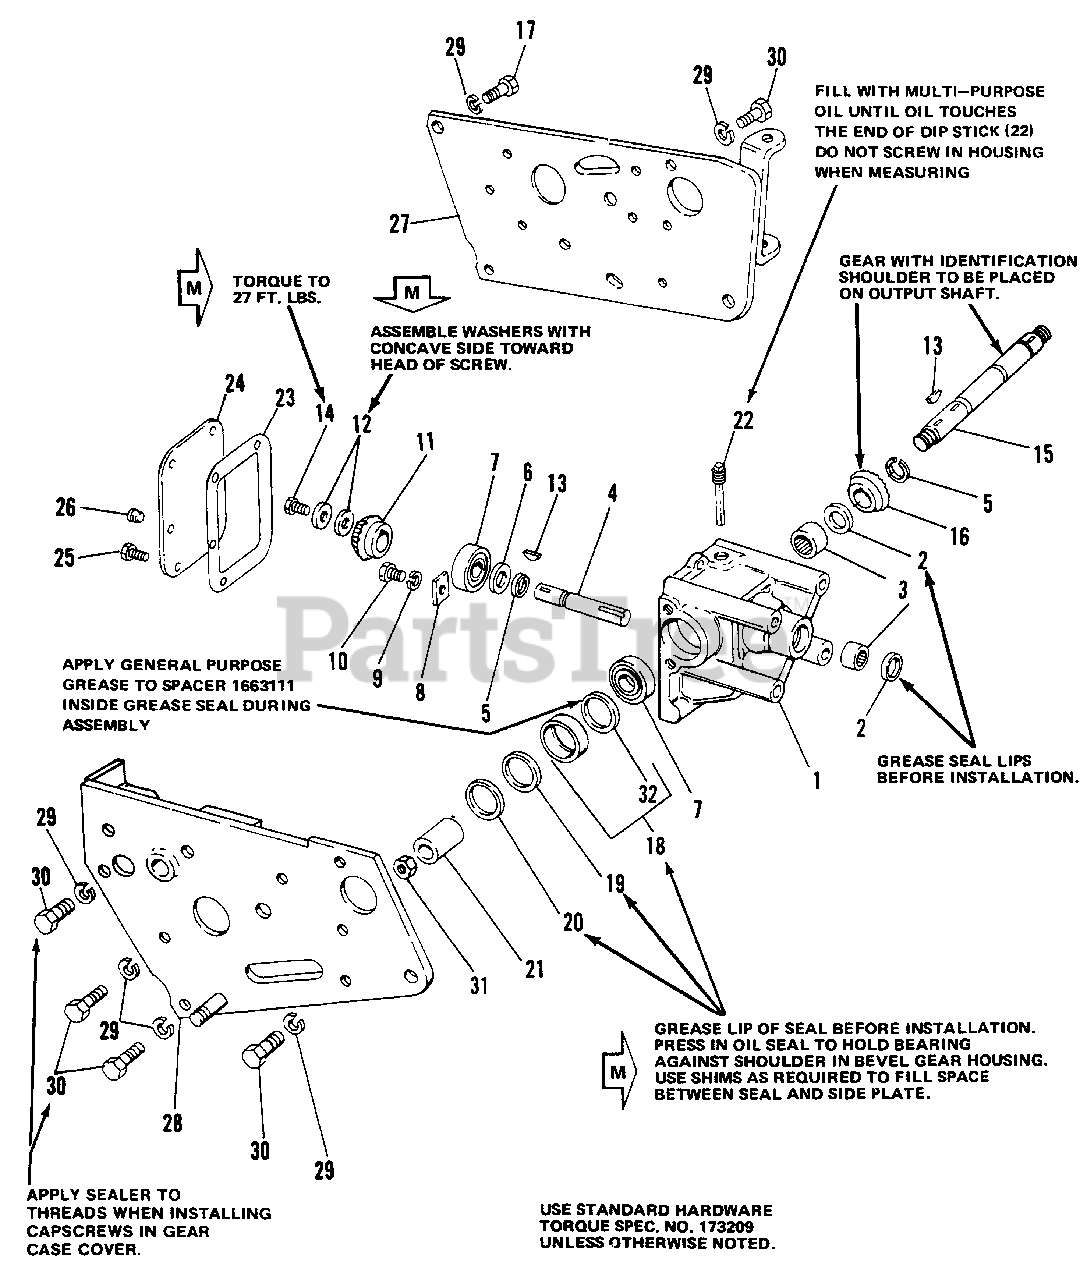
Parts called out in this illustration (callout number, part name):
1	HOUSING, Bevel Gear
3	BEARING, Needle
4	SHAFT, Driver
5	RING, Retaining
7	BEARING, Ball
8	PLATE, Bearing Clamp
9	LOCKWASHER, 5/16
10	CAPSCREW, Hex Hd., 5/16-18 x 5/8
11	GEAR, Bevel Driver
13	KEY, Woodruff, No. 9
14	CAPSCREW, Hex Hd., 5/16-18 x 3/4
15	SHAFT, Driven
16	GEAR, Bevel Driven
17	CAPSCREW, Hex Hd., 7/16-14 x 1-1/4
18	SEAL, Oil Kit, (Replaces 171787)
25	CAPSCREW, Hex, 1/4-20 x 5/8
27	PLATE ASSY, Side, L.H.
28	PLATE ASSY, Side, R.H.
29	LOCKWASHER, 7/16
30	CAPSCREW, Hex Hd., 7/16-14 x 1
31	LOCKNUT, Hex, Jam, 3/4-16
32	SPACER, Oil Seal
